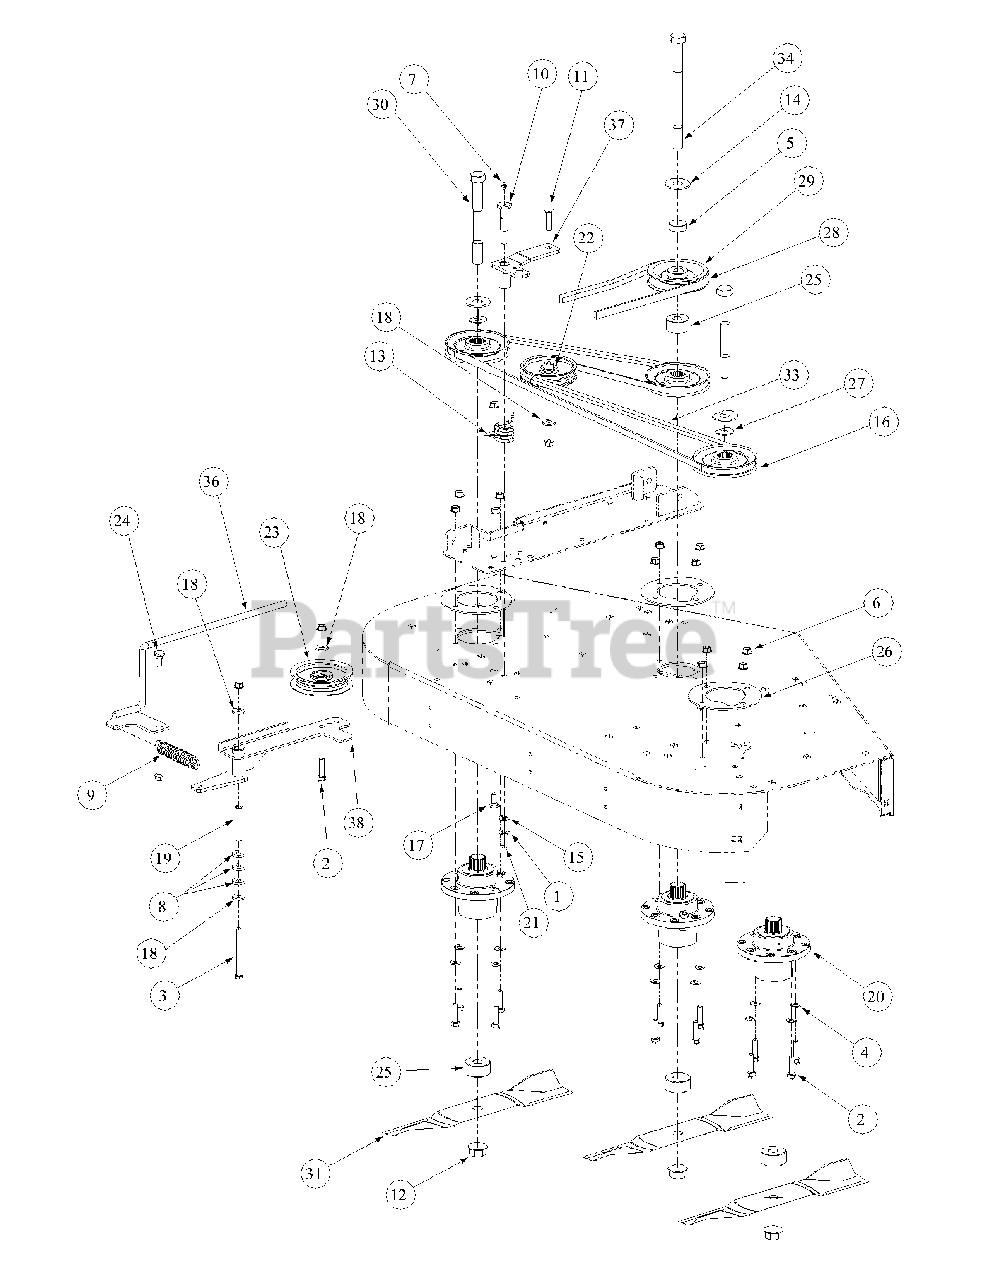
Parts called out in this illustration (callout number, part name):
1	Lock Washer, 7/16
2	Hex Cap Screw, 3/8-16 x 1-1/2
3	Hex Cap Screw, 3/8-16, 3.75
4	Flat Washer, 3/8
6	Hex Nut, Flange Lock, 3/8-16
7	Grease Fitting, 1/4-28 x 3/16
8	Idler Washer
9	Spring Extension, 1.0 OD x 5.125
10	Shoulder Screw, 7/16-14
11	Hex Carriage Screw, 3/8-16, 1.75
12	Hex Flange Nut, 3/4-16
13	Torsion Idler Spring
14	Flat Washer, .781 ID, 2.00 OD, .105
15	Flat Washer, .469 ID, .875 OD, .105
16	V-Pulley, 4.65 OD
17	Carriage Bolt, 3/8-16 x 1
18	Flat Washer, .406 ID, 1.0 OD, .105
19	Spacer, .39 ID x .625 OD x 2.75
20	Aluminum Spindle Assembly
21	Hex Nut, 7/16-14
22	Flat Pulley
23	Idler Pulley, 4.06 OD w/Deep Flange
24	Shoulder Screw, .50 x .27 Lg., 3/8-16
25	Spacer, .760 ID x 2.000 OD x 1.1
26	Spindle, Aluminum Cast Support Plate
27	Spacer, .812 ID x .268 LG
28	V-Belt, B Section x 83.2
29	V-Pulley, 4.75 OD
30	Hex Cap Screw, 3/4-16, 7.00
31	Blade, 17.0, Hi-Lift, 0.756 ID
33	V-Belt, A Section x 105.3
34	Hex Cap Screw, 3/4-16, 9.00
36	Spring Tension Rod Assembly
37	Idler Arm Assembly, Deck Spindle
38	Idler Arm Assembly, Flat Top Bearing
